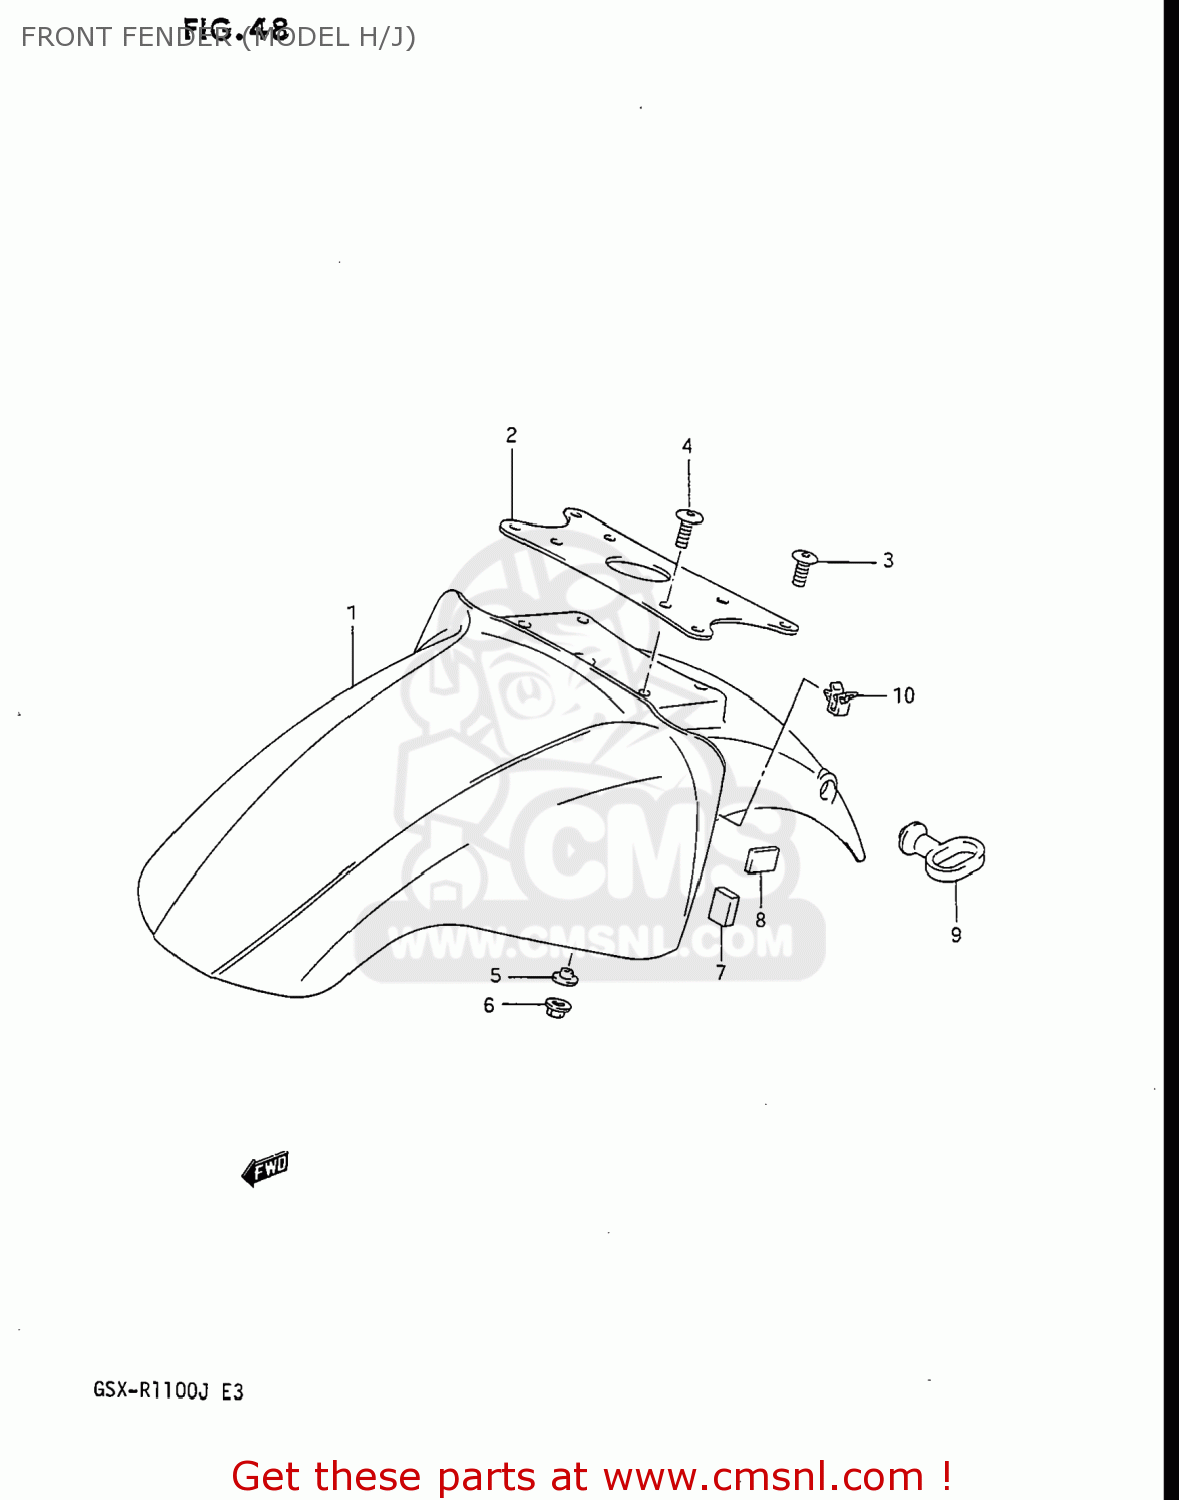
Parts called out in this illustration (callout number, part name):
1	FENDER,FRONT
2	BRACE,FRONT FENDER
3	SCREW(8X16)
4	SCREW(5X14)
5	WASHER
6	NUT
7	CUSHION,FRONT FENDER,FRONT
8	CUSHION,FR FENDER SIDE
9	GUIDE,CABLE
10	CLIP
